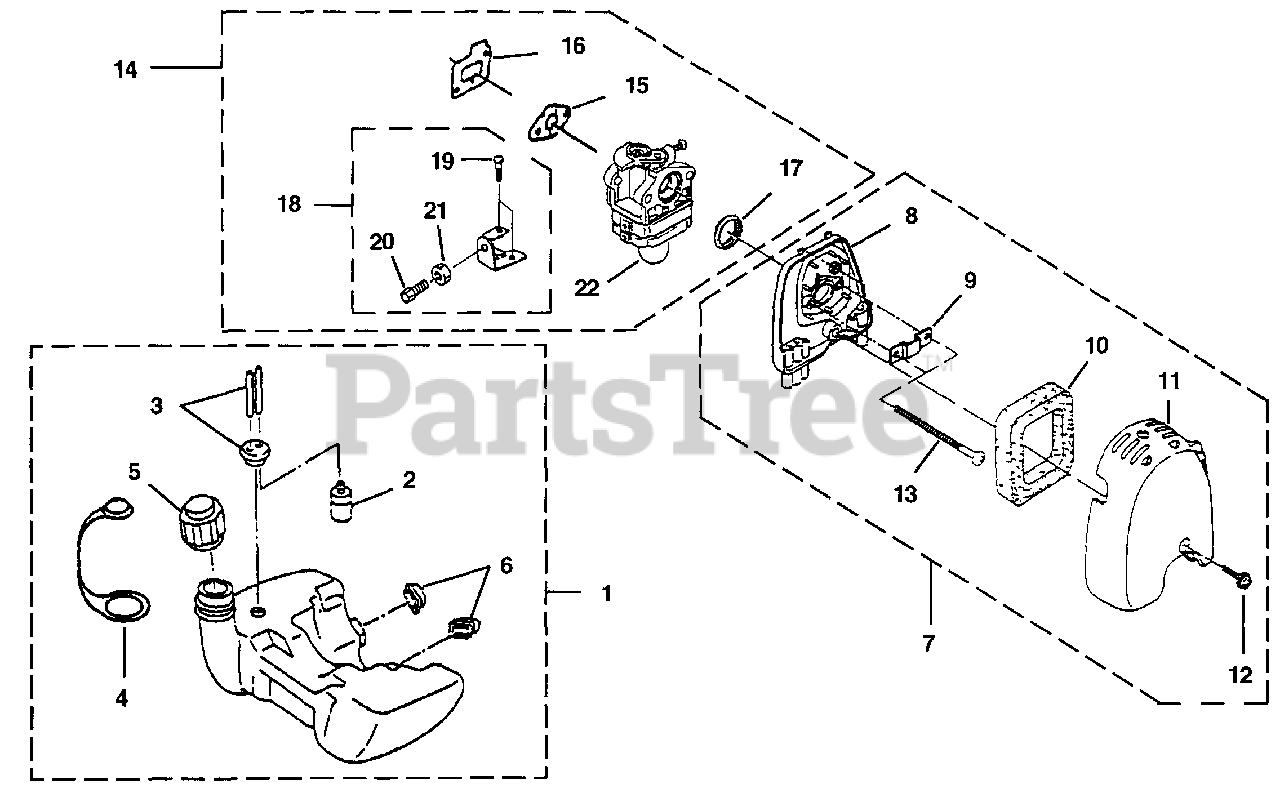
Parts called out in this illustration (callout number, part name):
1	FUEL TANK ASSEMBLY
2	FILTER - Fuel
4	CAP - Retainer
5	CAP - Fuel
6	RUBBER BUMPER KIT
7	AIR FILTER ASSEMBLY
8	BODY - Air Filter
9	PLATE - Air Filter
10	FILTER - Air
11	COVER - Air Filter
12	SCREW ASSEMBLY (M5 x 14)
13	SCREW (M5 x 50)
14	CARBURETOR ASSEMBLY
15	GASKET - Carburetor
16	GASKET - Heat Dam
17	RING - Packing
18	CABLE BRACKET ASSEMBLY
19	SCREW - Throttle Collar (M5 x 18)
20	SCREW - Cable Adjust
21	NUT - Cable Adjust
22	PRIMER BULB
